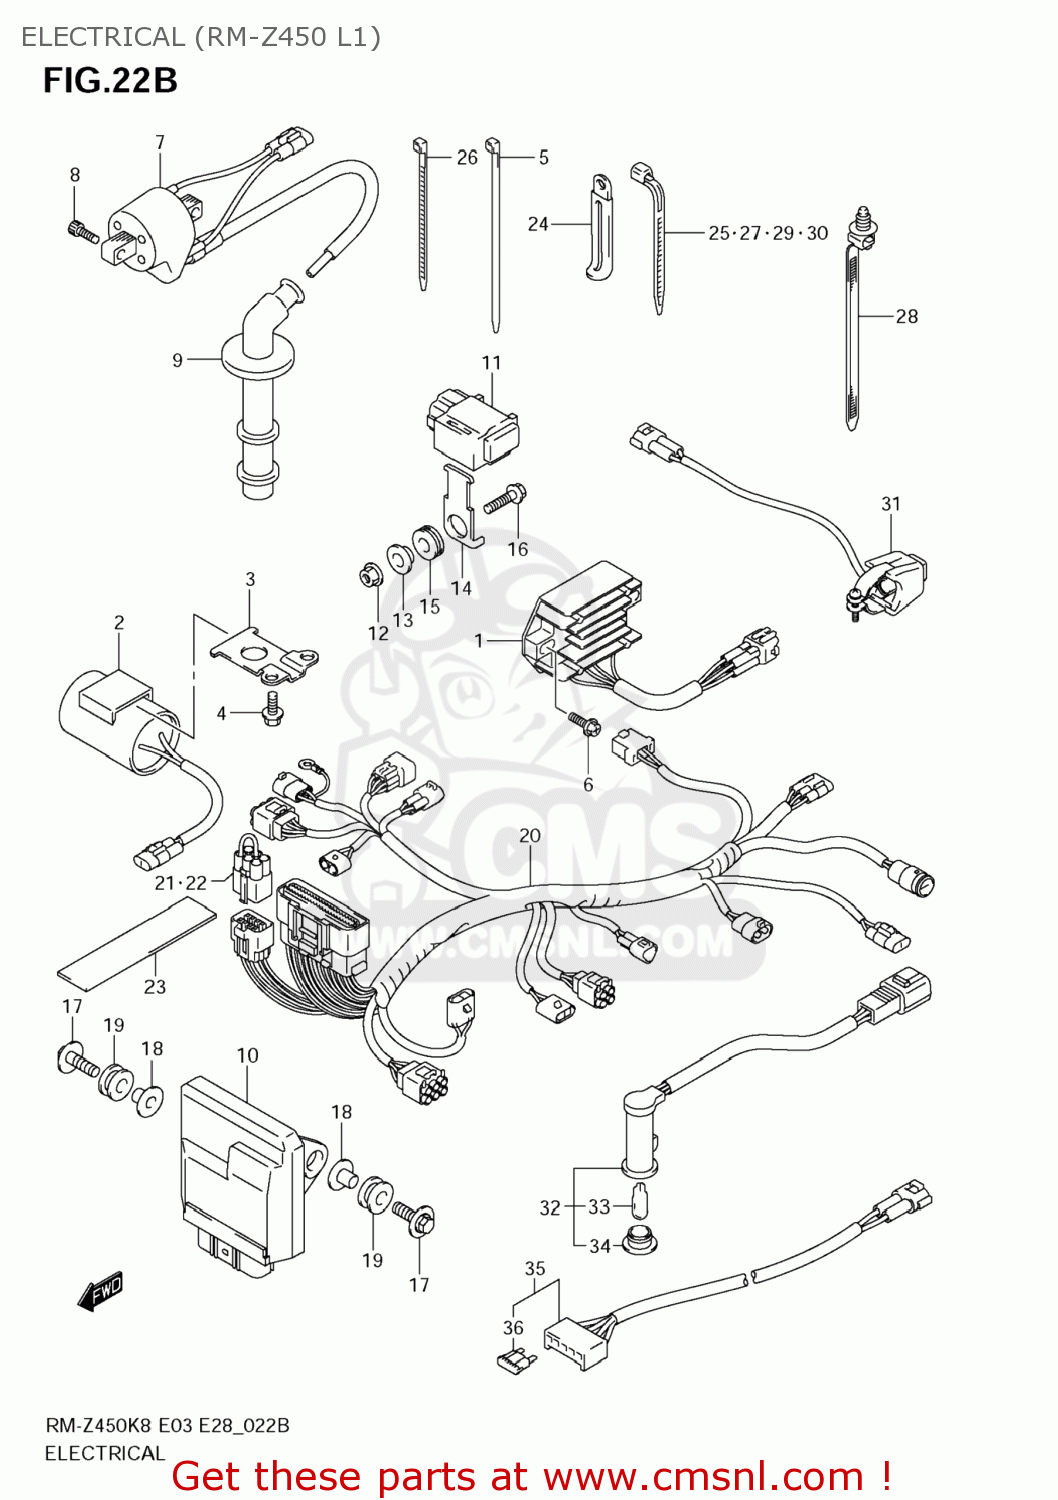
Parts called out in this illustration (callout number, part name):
1	RECTIFIER ASSY
2	CONDENSER ASSY
3	BRACKET,CONDENSER
4	BOLT(6X10)
5	CLAMP(L:100)
6	SCREW
7	COIL ASSY,IGNITION
8	BOLT
9	CAP ASSY,SPARK PLUG
10	CONTROL UNIT,FI
11	SENSOR ASSY,FUEL CUT
12	NUT
13	SPACER(6.2X8.4X10.9)
14	BRACKET,FUEL CUT SENSOR
15	CUSHION
16	BOLT
17	BOLT(6X20)
18	SPACER(6.2X8.4X10.9)
19	GROMMET
20	HARNESS,WIRING
21	WIRE,SHORT
22	WIRE,SHORT
23	COVER,HARNESS
24	CLAMP(L:45)
25	CLAMP(L:95)
26	CLAMP(L:95)
27	CLAMP(L:125)
28	CLAMP(L:154)
29	CLAMP(L:165)
30	CLAMP(L:235)
31	SWITCH ASSY,ENGINE STOP
32	LAMP ASSY,FI INDICATOR
33	BULB(12V3.4W,T10)
34	LENS(RED)
35	WIRE,BATTERY
36	FUSE(10A)
